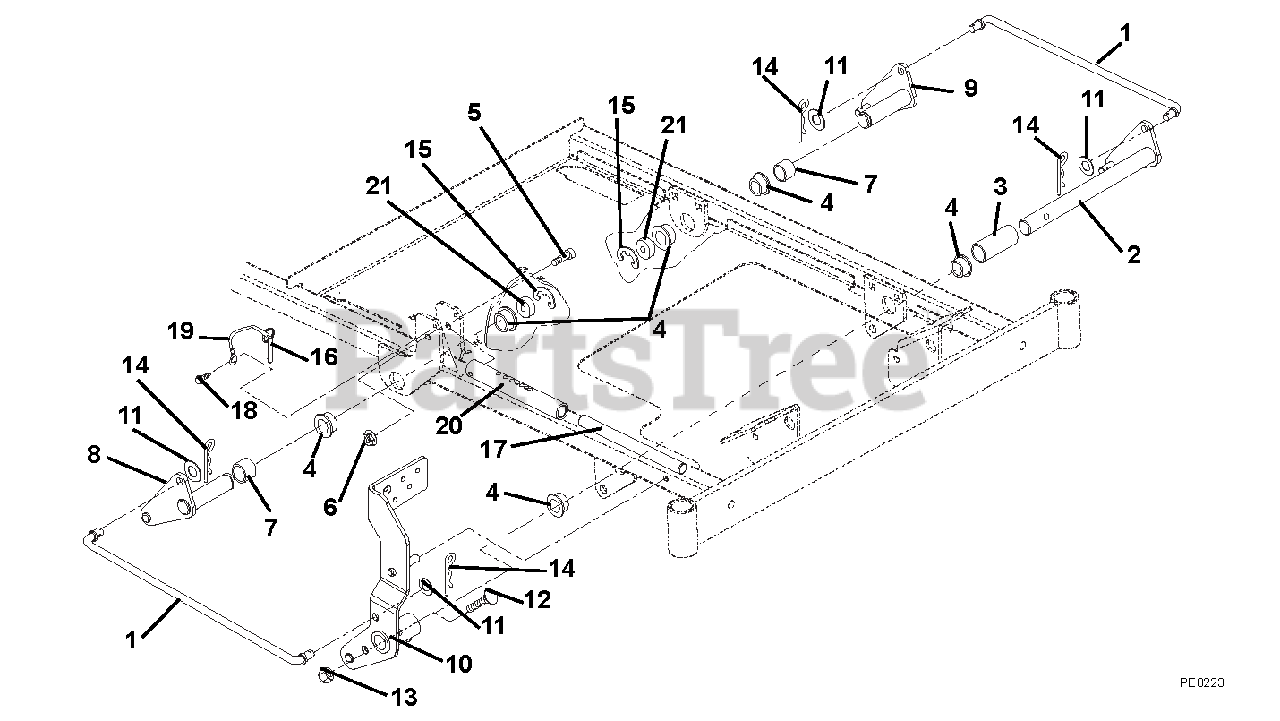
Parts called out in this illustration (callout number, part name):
1	ROD, LIFT
2	WELDMENT,FRONT LIFT
3	BSHG, SPCR 1.01X1.25X2.63 PM
4	BSHG-FLG 1.000X1.12X.62X1.50BR
5	@BLT-HEX .38-16X2.75 GR5 YWZC
6	@NUT-LK-NYL-FLG .38-16 YWZC
7	BSHG-SPCR 1.032X1.250X.88 PM
8	WELDMENT, LIFT, REAR - RH
9	WELDMENT, LIFT, REAR - LH
10	WMT, FOOT PEDAL
11	@WSHR-FL-STL.531X1.06X.095YWZC
12	@BLT-HEX .38-16X2.00 GR5 YWZC
13	@NUT-LK-NYL-FLG .38-16 YWZC
14	PIN, HAIR, EXT - #16 YWZC
15	RG-RTNG .822X1.500X.050 TYP E
16	PIN, SPRING BALL .375OD X 1.50
17	ROD, LIFT
18	@SCR-TAP .25-20X.37 HWH YWZ TR
19	CBL,HOOD
20	TUBE, LIFT STOP
21	BSHG, SPCR 1.032X1.25X.25 PM
